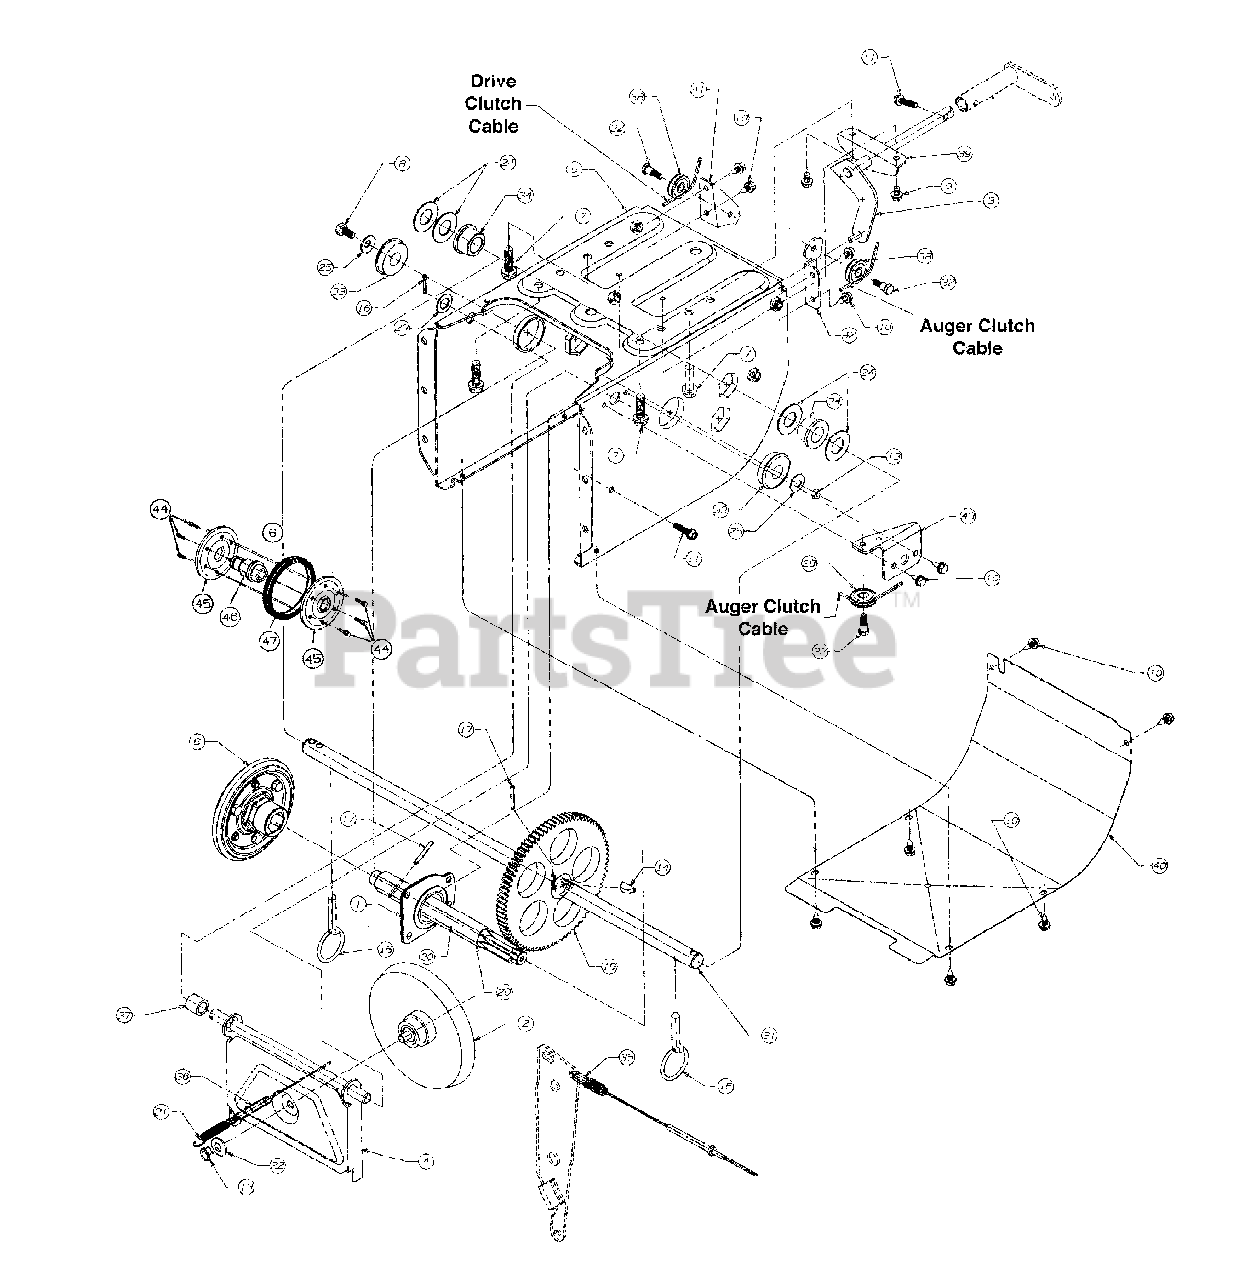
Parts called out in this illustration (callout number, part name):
1	Bearing Ass'y.
2	Ass'y., Friction Wheel Disc
3	Rod Shift, Wheel Drive
4	Brkt. Ass'y. Friction Wheel
7	Hex Self-Tap Screw
9	Scr., Hex Wash. Hd., TT 1/4-20 x .5"
10	Hex Self-Tap Scr.
11	Screw, Hex
13	Nut, Hex
14	Key
15	Pin, Klick
16	Pin, Cotter
17	Pin, Roll
20	Shaft, Hex
21	Extension Spring
22	Washer, Bell
23	Flat Washer
24	Washer, Flat
25	Washer, Bell
30	Lubricant
31	Axle
32	Screw, Shoulder
33	Bearing, Ball
34	Flange Bearing
35	Cable, Auger
36	Cable, Clutch
37	Spacer
38	Roller, Cable
42	Brkt., Auger Clutch Cable Guide
43	Brkt., Front Support Guide
44	Hex Wash Hd. TT-Tap Scr. 1/4-20 x .5" Lg.
45	Friction Plate
46	Friction Wheel Hub
47	Friction Wheel Rubber
